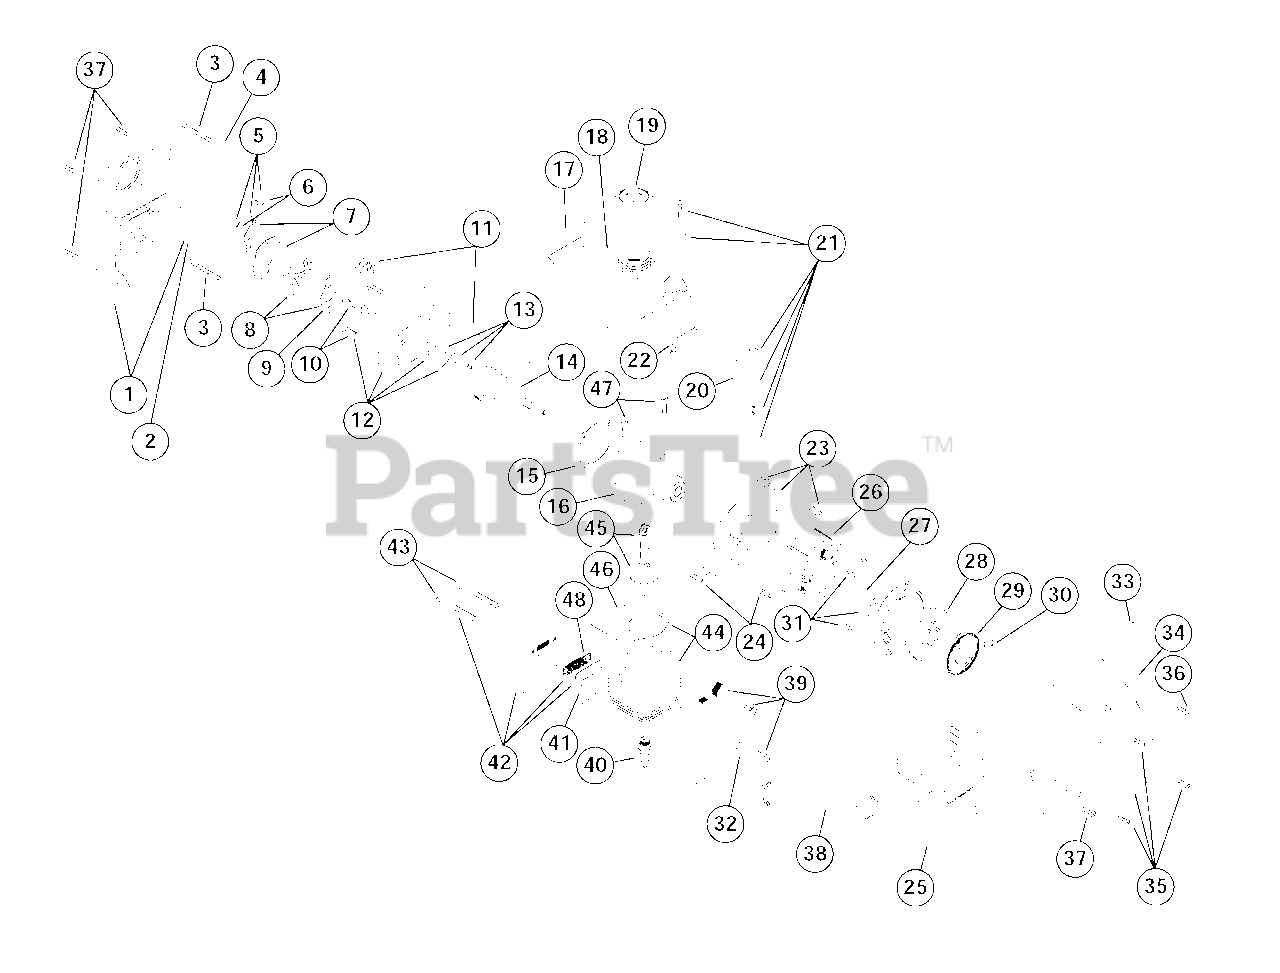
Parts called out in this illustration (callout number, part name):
1	Air Cleaner/Muffler Cover Assembly
2	Air Cleaner Filter
3	Carburetor Mounting Screw Assembly
4	Wavey Washer
5	Choke Lever Assembly
6	Choke Knob and Screw
7	Choke Lever and Plate
8	Carburetor Assembly
9	Carburetor Gasket
10	Carb Mount Screw
11	Primer and Hose Assembly
12	Carb Mount Assembly
13	Reed Assembly
14	Power Shaft Assembly
15	Rear Cover Gasket
16	Crankcase Service Assembly
17	Rear Mounting Pad
18	Fuel Tank Assembly
19	Fuel Cap Assembly
20	Fuel Return Line
21	Fuel Line Assembly
22	Front Mounting Pad
23	Shroud Assembly
24	Shroud Screw
25	Shroud Extension and Stand
26	Flywheel Assembly
27	Nut, Square Drive
28	Recoil Pulley Assembly
29	Recoil Spring
30	Rope Guide
31	Pulley Retainer Assembly
32	Ground Tab
33	Pull Handle
35	Starter Housing Assembly
36	Housing Screw
37	Cover Screw
38	Wire Lead
39	Module Assembly
40	Spark Plug
41	Exhaust Gasket
42	Muffler Assembly
43	Muffler Mounting Bolt Assembly
44	Cylinder Assembly
45	Piston and Rod Assembly
46	Cylinder Gasket
47	Cylinder Bolt
48	Spark Arrestor Screen
